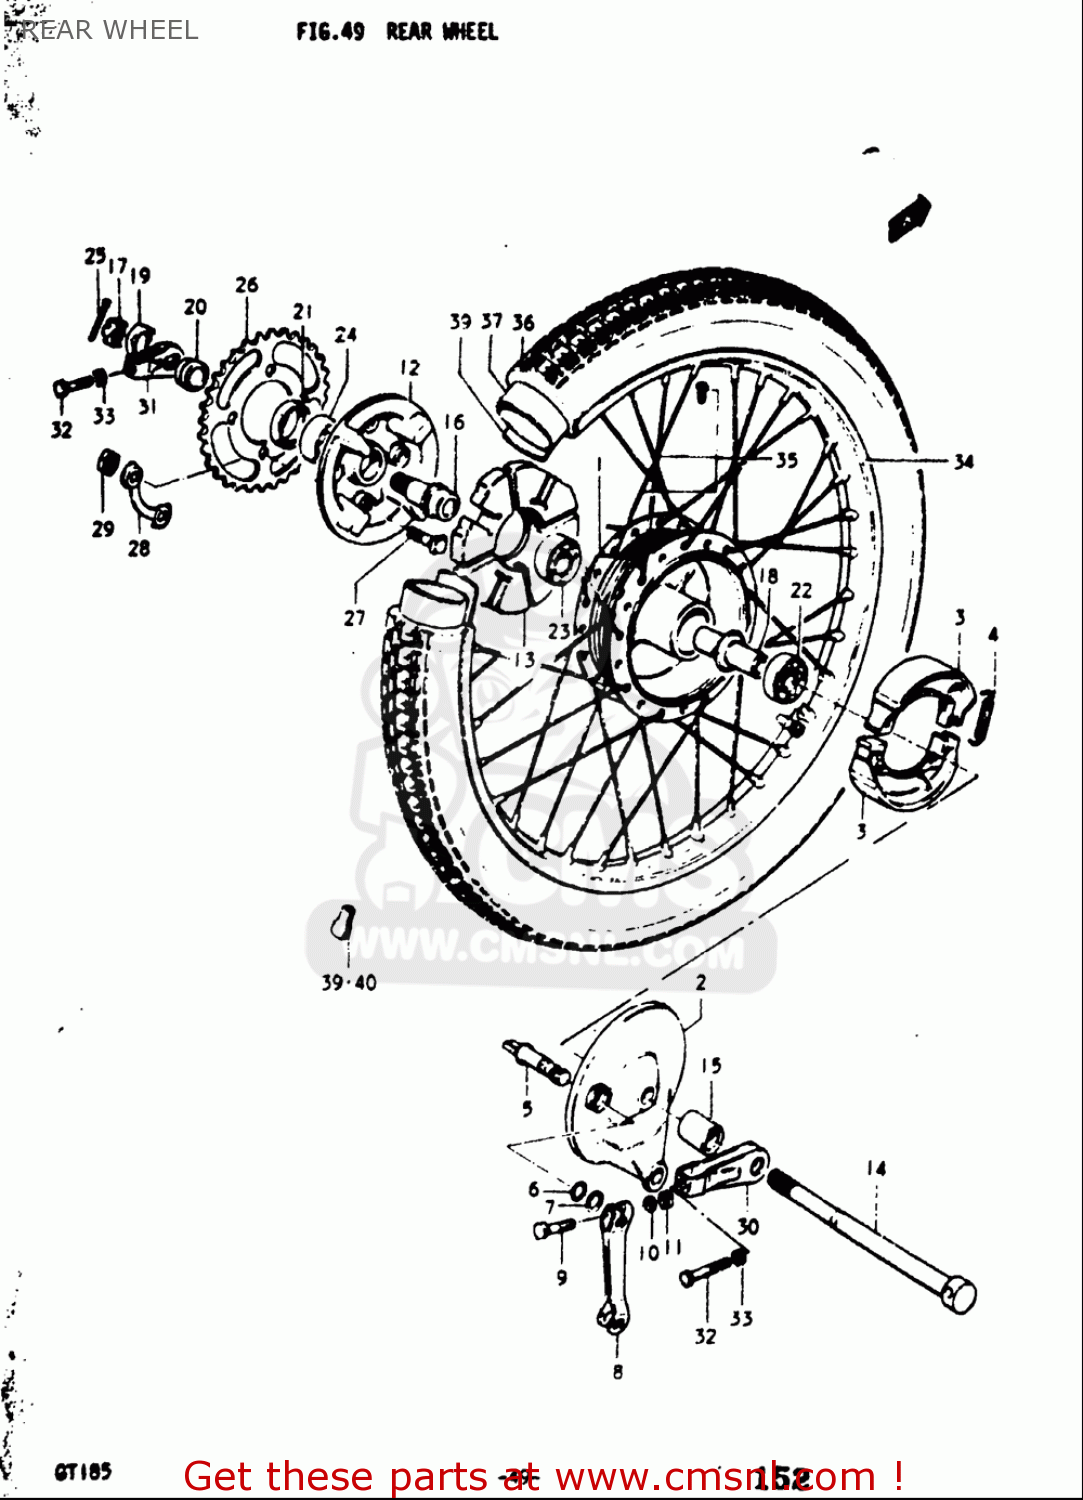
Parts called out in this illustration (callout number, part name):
1	HUB,RR
4	SPRING(L:35.8)
5	CAM,FR BRAKE
6	O RING(D:2.5,ID:11.4)
7	WASHER(12.5X20X1)
8	LEVER,REAR BRAKE CAM
9	BOLT(6X31)
10	WASHER
11	NUT
13	ABSORBER ASSY,HUB SHOCK
14	AXLE,REAR
15	SPACER(15.2X26X33)
17	NUT 12MM
19	NUT
20	SPACER (20X28X19)
21	SEAL,OIL(28X47X7)
22	BEARING
23	BEARING
24	BEARING(20X47X14)
25	PIN
26	SPROCKET,REAR 40T
27	BOLT(8X33.5)
28	WASHER
29	NUT
30	ADJUSTER,CHAIN
31	ADJUSTER,CHAIN,L
32	BOLT(8X50)
33	NUT
34	RIM,FR WHEEL 1.60X18
35	SPOKE SET,RR
36	TIRE,RR(3.00-18)
37	TUBE ASSY,WHEEL INNER
38	PROTECTOR,INNER TUBE
39	BALANCER,WHEEL (B)
40	BALANCER,WHEEL (30G)
